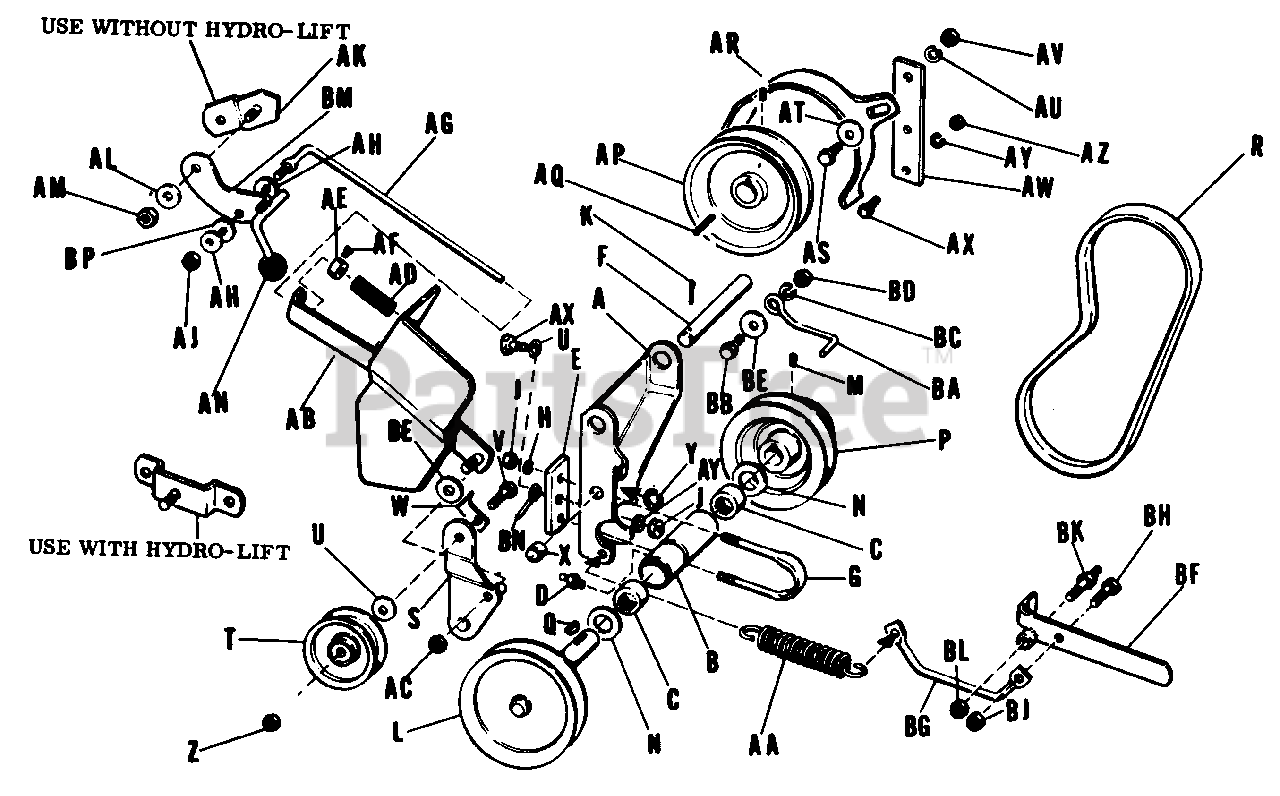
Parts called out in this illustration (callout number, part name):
A	P.T.O.-Bracket
B	Bearing Housing
C	Needle Bearing
D	Grease Fitting
E	Support Plate
F	Pivot Rod, 5/8" Dia. x 6-13/16"
H	Lock Washer, 5/16"
J	Full Hex. Nut, 5/16"-18
K	Cotter Pin, 3/16" Dia. x 1-1/2"
L	Shaft Assembly, P.T.O.
M	Set Screw, 5/16"-18 x 5/16"
P	P.T.O. Pulley
Q	Woddruff Key #9-3/16" x 3/4"
S	Idler Lever Assembly
T	Idler Pulley
U	Plain Washer, 5/16"
V	Hex. Cap Screw, 3/8"-16 x 1-1/4"
Y	Retaining Ring
Z	Full Hex. Nut, 3/8"-16
AA	Tension Spring
AB	Rod Guide Assembly
AC	Full Lock Hex. Nut, 3/8"-16
AF	Set Screw, 1/4"-20 x 3/8"
AG	Clutch Rod Assembly
AH	Plain Washer, 5/16"
AJ	Elastic Stop Nut, 5/16-18
AK	Pivot Bar Assembly
AL	Plain Washer, 3/8"
AM	Full Lock Hex. Nut, 3/8"-16
AN	Knob
AR	Belt Guard Assembly
AS	Hex. Cap Screw, 3/8"-16 x 1"
AT	Plain Washer, 3/8"
AU	Lock Washer, 3/8"
AV	Full Hex. Nut, 3/8"-16
AW	Belt Guard Support
AX	Hex. Cap Screw, 5/16"-18 x 1"
AY	Lock Washer 5/16"
AZ	Full Hex. Nut, 5/16"-18
BB	Hex Capscrew, 5/16-18 x 1" lg.
BC	Lock Washer, 5/16
BD	Hex Nut, 5/l6-18
BE	Plain Washer, 5/l6
BF	Handle Assembly
BG	Spring Tension Rod
BH	Hex. CapScrew, 5/16"-18 x 1-1/4"
BJ	Full Lock Hex. Nut, 5/16"-18
BL	Full Lock Hex, Nut, 7/16"-14.
BM	Clutch Lever Assembly
BN	Belt Guide
BP	Special Washer
